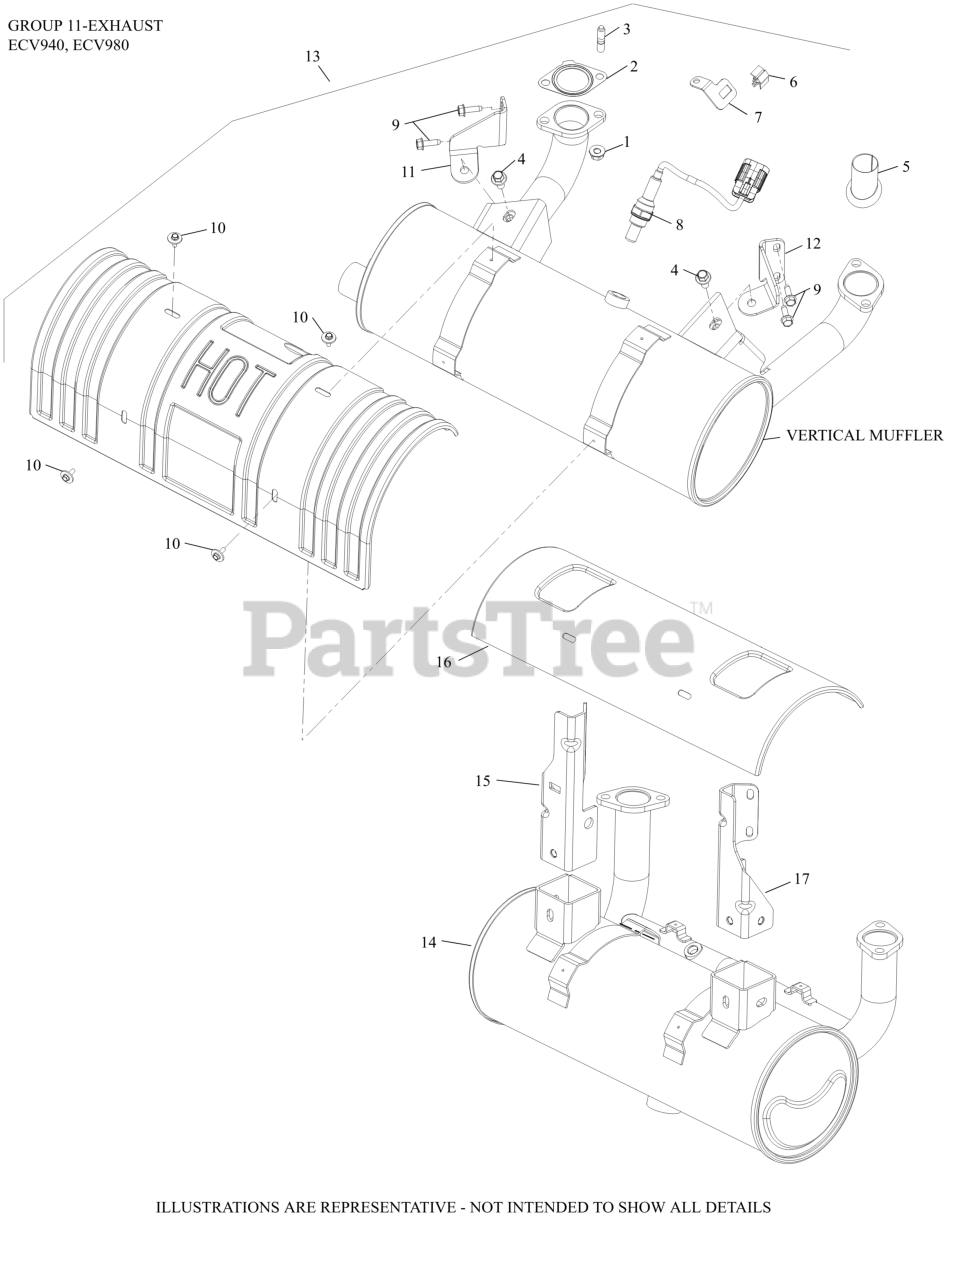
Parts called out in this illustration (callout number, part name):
1	NUT, HEX FLANGE LOCK (M8)
2	GASKET, EXHAUST
4	SCREW, THREAD FORMING
5	LINER, EXHAUST PORT
6	CLIP, O2 SENSOR
8	SENSOR, OXYGEN (M18 x 1.5 THREADS)
